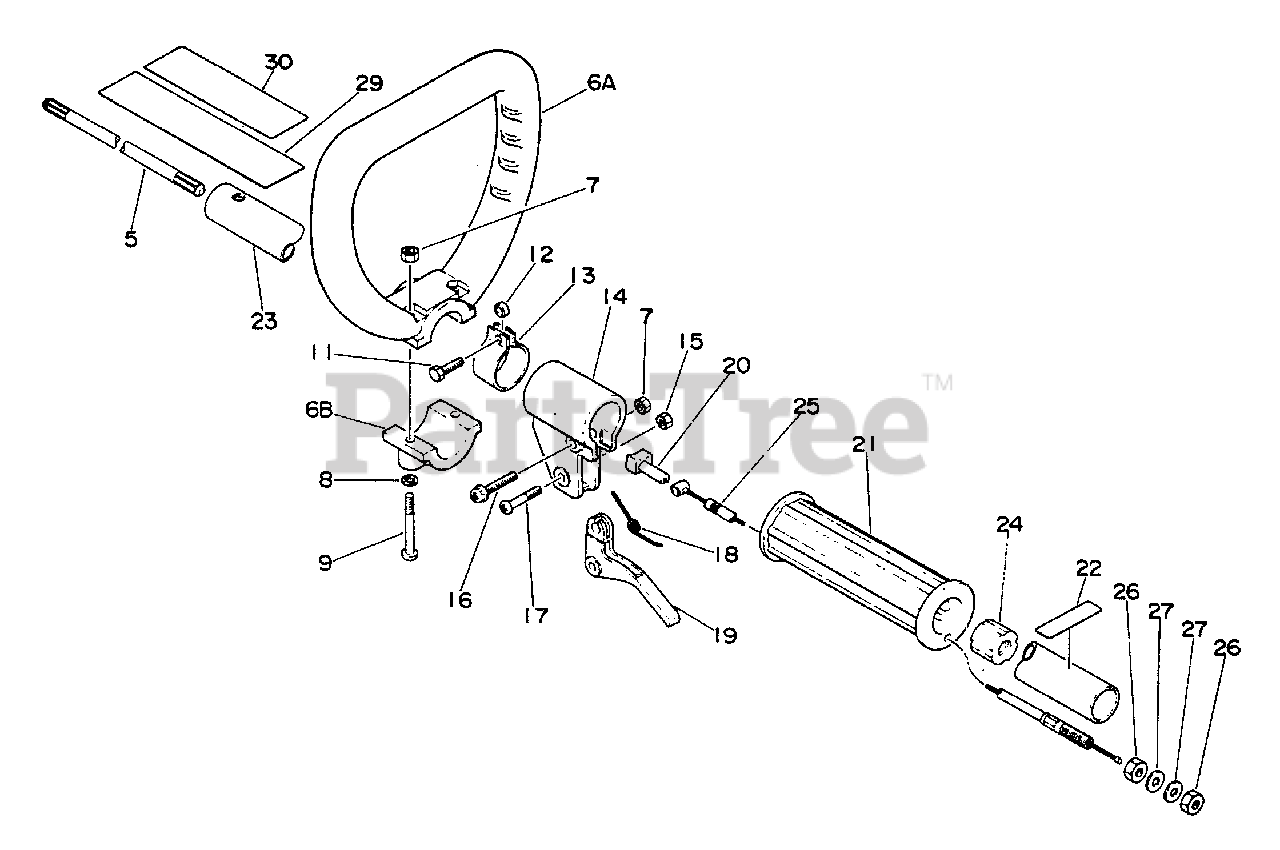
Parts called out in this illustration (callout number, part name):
5	DRIVESHAFT
6	LOOP HANDLE ASSY
6A	LOOP HANDLE ASSY
6B	LOOP HANDLE ASSY
7	NUT M5
8	WASHER, FLAT 5.5×10×0.8
9	SCREW 5×40
11	BOLT 5×18
12	SPACER, GUARD
14	BRACKET, TRIGGER
15	LOCKNUT - 5
16	SCREW 5×30
18	SPRING, THROTTLE
19	TRIGGER, THROTTLE
20	GUIDE, CABLE
21	GRIP
22	LABEL - ALIGNMENT
23	MAIN PIPE ASSY
24	STOPPER
25	CABLE, THROTTLE
27	WASHER 6.5×11.5×0.8
29	LABEL - CAUTION
